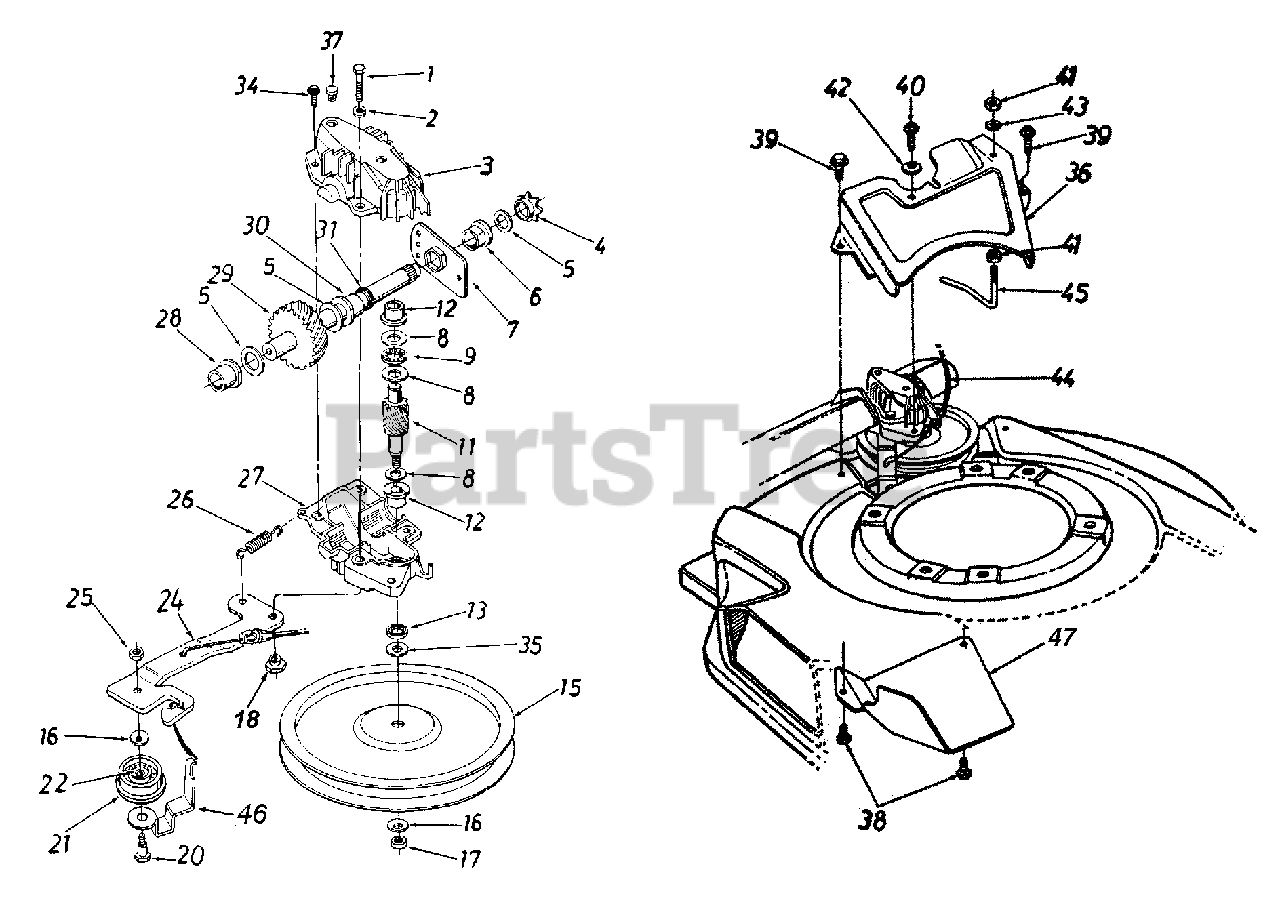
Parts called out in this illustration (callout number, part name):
1	Hex Bolt 1/4-20 x 1.25" Lg.
2	L-Wash. 1/4" I.D.
3	Upper Hsg. Half
4	#48 Sprocket 7 Tooth x 1/2 Pitch
5	Fl-Wash. 5/8" I.D. x .030
6	Hex Flange Brg. .631" I.D.
8	Thrust Wash. .382" I.D. x .70" O.D.
9	Thrust Bearing .375" I.D. x .812" O.D.
11	11 Tooth Helical Gear
12	Flange Bearing
13	Oil Seal
15	Fl-Pulley 5.06" I.D.
16	Bell-Wash. .265" I.D. x .75"
17	Hex Nut 1/4-28 L.H. Thd.
18	Shld. Spacer .375" Dia. x .170
20	Shld. Bolt .375" Dia. x .40"
21	Fl-Idler Plastic 1.50" Dia.
22	Needle Brg. .375" x .375"
24	Idler Brk't. Ass'y.
25	Hex Patch L-Nut 1/4-28 Thd.
26	Extension Spring 1.12" Lg.
27	Lower Hsg. Half
28	Flange Bearing .56 Dia.
29	Shaft Ass'y.
30	Flange Bearing .629 Dia.
31	Oil Seal .625 Dia.
34	Scr. AB #10-16: .750 Hx Ind Wsh.
35	Hex Washer .26" x .88"
38	Hex B-Tap Scr. 1/4-20:.375 Lg.
39	Hex AB-Tap Scr. 1/4 x .50" Lg.
40	Hex B-Tap Scr. 1/4 x .62" Lg.
41	Hex Nut 1/4-20 Thd.
42	Bell-Wash. .265" I.D. x .75"
43	L-Wash. 1/4" I.D.
44	S.P. Cable - 48" Lg.
45	S.P. Belt Guard
46	Belt Guard
